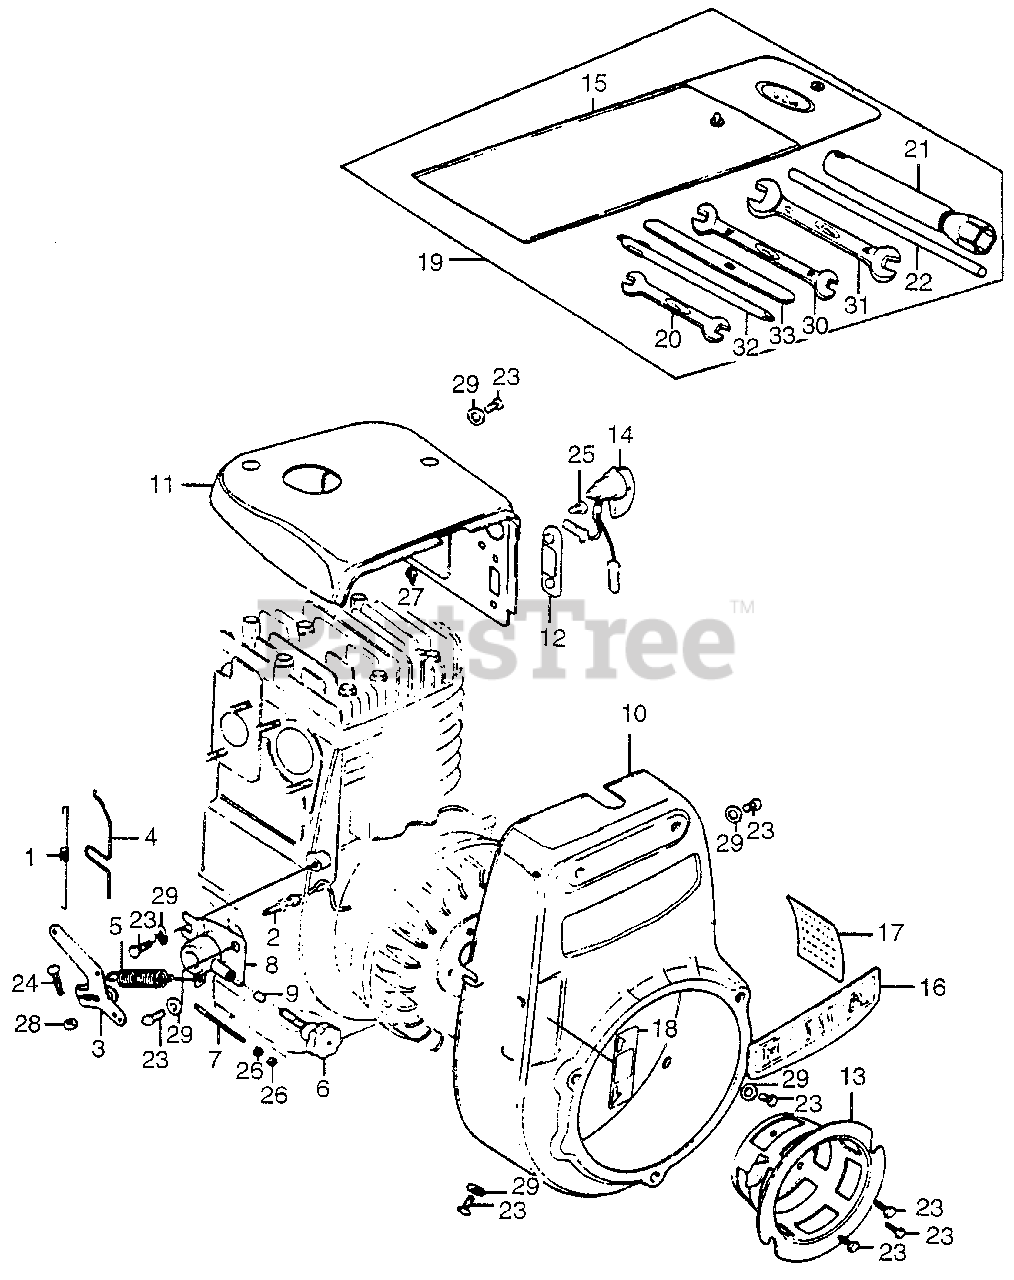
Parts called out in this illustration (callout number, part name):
1	SPRING, THROTTLE RETURN (NOT AVAILABLE)
2	SHAFT, GOVERNOR ARM
3	ARM, GOVERNOR
4	ROD, GOVERNOR
5	SPRING, GOVERNOR
6	SCREW, GOVERNOR ADJUST (NOT AVAILABLE)
7	BOLT, SPRING ADJUSTING (NOT AVAILABLE)
8	LEVER, CONTROL (NOT AVAILABLE)
9	BUSHING, CONTROL
10	COVER, FAN *R8* (BRIGHT RED) (NOT AVAILABLE)
11	COVER, SIDE *R8* (BRIGHT RED)
12	DEFENDER, SIDE COVER
13	PULLEY, STARTER (NOT AVAILABLE)
14	SWITCH ASSY., ENGINE STOP (NOT AVAILABLE)
16	EMBLEM (NOT AVAILABLE)
17	MARK, DIPSTICK OIL (NOT AVAILABLE)
18	PLATE, THROTTLE
19	TOOL ASSY.
19	TOOL KIT
20	WRENCH (8X9)
21	WRENCH, SPARK PLUG (NOT AVAILABLE)
22	HANDLE, BOX WRENCH
23	BOLT, HEX. (6X12)
24	BOLT, HEX. (6X16)
25	SCREW, PAN (5X8)
25	SCREW, PAN (5X10)
26	NUT, HEX. (4MM)
27	NUT, HEX. (5MM)
28	NUT, HEX. (6MM)
29	WASHER, PLAIN (6MM)
30	WRENCH (10X12) (OPEN END)
31	WRENCH (14X17) (OPEN END)
32	SCREWDRIVER 1, PHILLIPS (NO.2)
33	LEVER, TIRE
